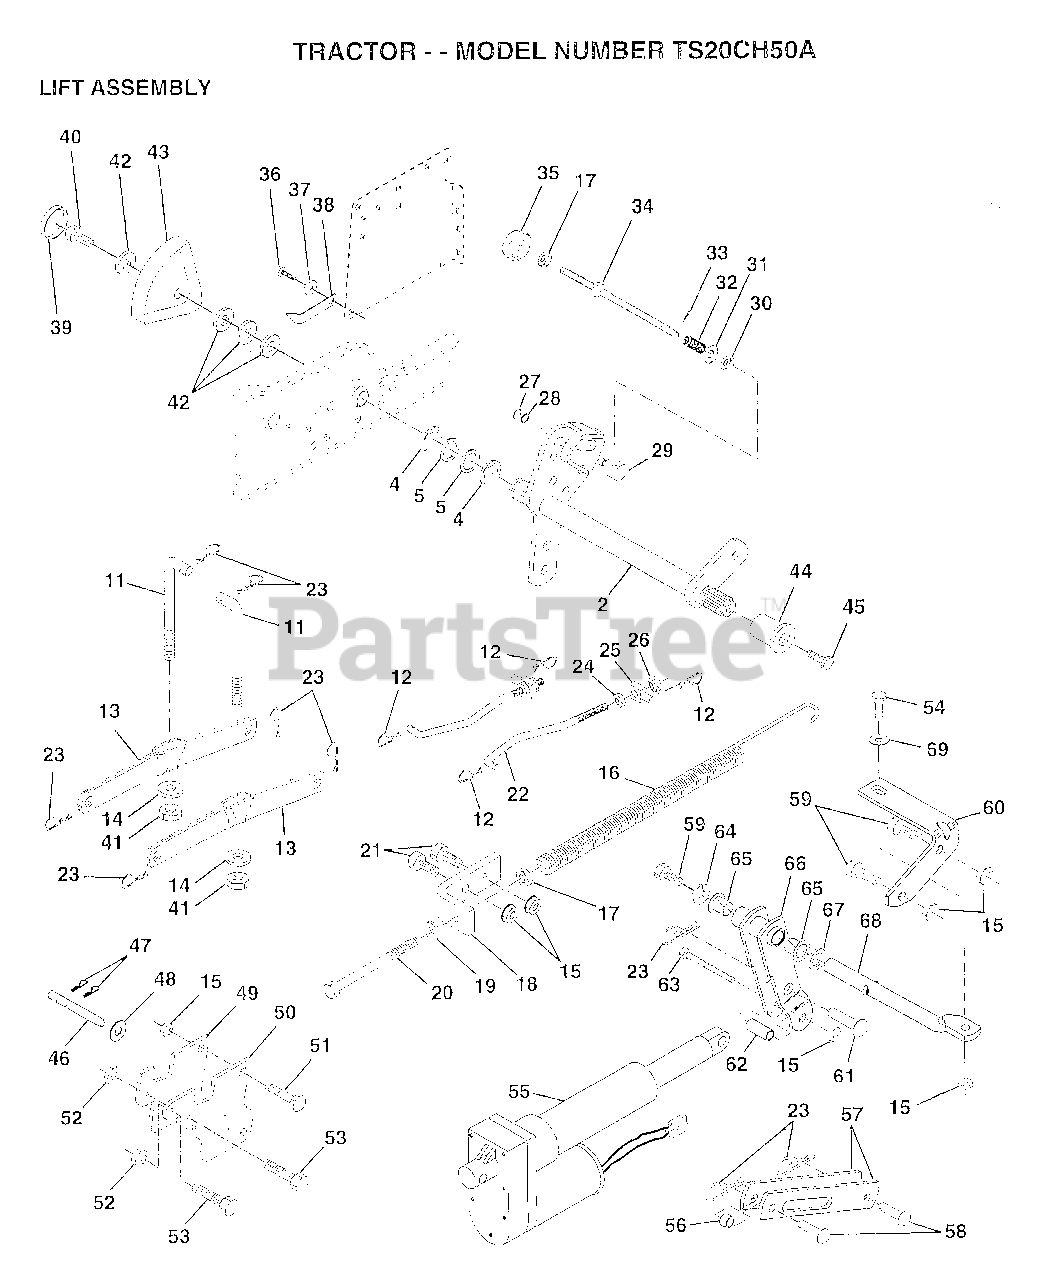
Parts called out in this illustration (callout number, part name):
2	SHAFT.LIFT.VGT.95
4	E-RING
5	WASHER
11	LINK.LIFT.MWR.VGT
12	RETAINER.SPRING
13	ARM SUSP REAR
14	BEARING PVT LH
17	NUT
18	BRACKET SPRING AS
19	WASHER
20	BOLT-ADJ SPRING T
21	BOLT
22	LINK.FRONT
24	NUT
25	TRUNION
26	NUT.LK.W/WSH.1/2.
27	KLIP RING
28	WASHER
29	TRUNION LT
30	NUT T
31	WASHER
32	SPRING.COMP.INF.H
34	ROD.ADJ.LIFT
35	KNOB INF 3/8-16
36	SCREW
37	WASHER T
38	POINTER HGT IND
39	"PLUG,HOLE"
41	NUT.CROWNLOCK.3/8
42	WASHER
43	HEIGHT INDICATOR
44	LIFT HUB-LEVE T
45	BOLT
46	PIN.ACTUATOR
48	WASHER
49	BRACKET.ACTUAT.LH
50	BRACKET.ACTUAT.RH
51	BOLT.3/8-14X1.25
52	NUT.7/16
53	BOLT.HX.HD.7/16
55	ACTUATOR.07823175
56	SPACER.500X384X23
57	LINK.LIFT.ELECT.
58	PIN.PIVOT
60	BRACKET.ROD.PIVOT
61	PIN.PIVOT
62	TUBE GT
63	BOLT-HEX EAK
64	LOCKWASHER
65	NYLINER.ROD.PIVOT
66	ARM.ASM.PIVOT
67	WASHER
68	ROD.SUPPORT.PIVOT
69	WASHER
